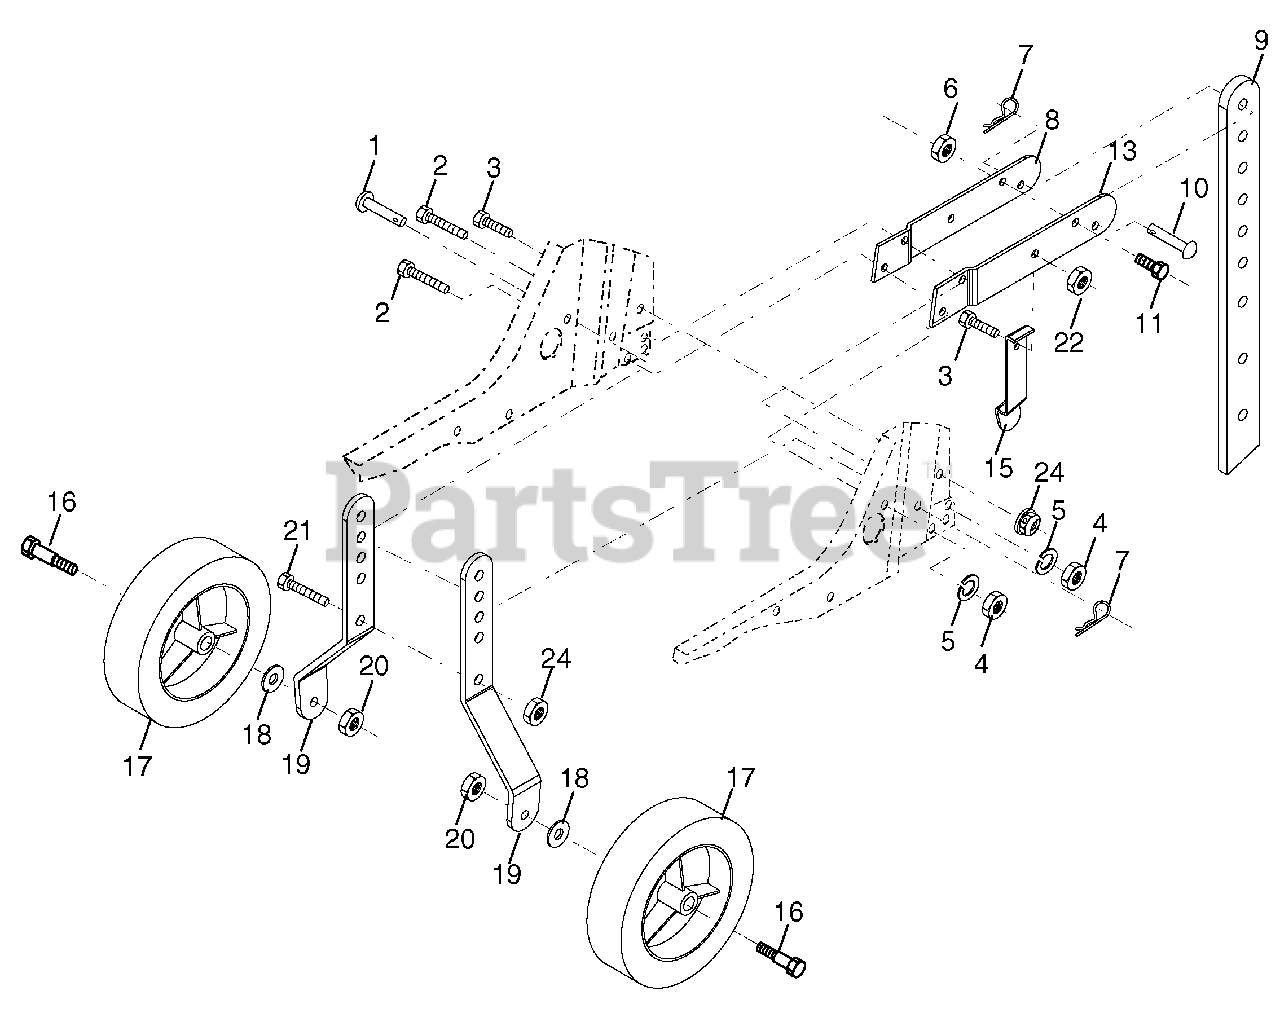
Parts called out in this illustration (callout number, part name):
1	Pin, Clevis
2	Bolt, Hex Head 5/16-18 x 1-1/4
3	Bolt, Hex Head 5/16-18 x 3/4
4	Nut, Hex 5/16-18
5	Washer, Lock 5/16
6	Locknut, Washer Insert 3/8-16
7	Clip, Hairpin
8	Support, Depth Stake, R.H.
9	Stake, Depth
10	Pin, Clevis
11	Bolt, Hex Head 3/8-16 x 1-3/4
13	Support, Depth Stake, L.H.
15	Spring, Stake
16	Bolt, Shoulder
18	Washer 13/32 x 13/16 x 11 Gauge
19	Bracket, Wheel
20	Nut, Hex, Crownlock 3/8-16
21	Bolt, Hex Head 5/16-18 x 1
22	Locknut, Washer Insert 5/16-18
24	Nut, Hex, Flangelock
